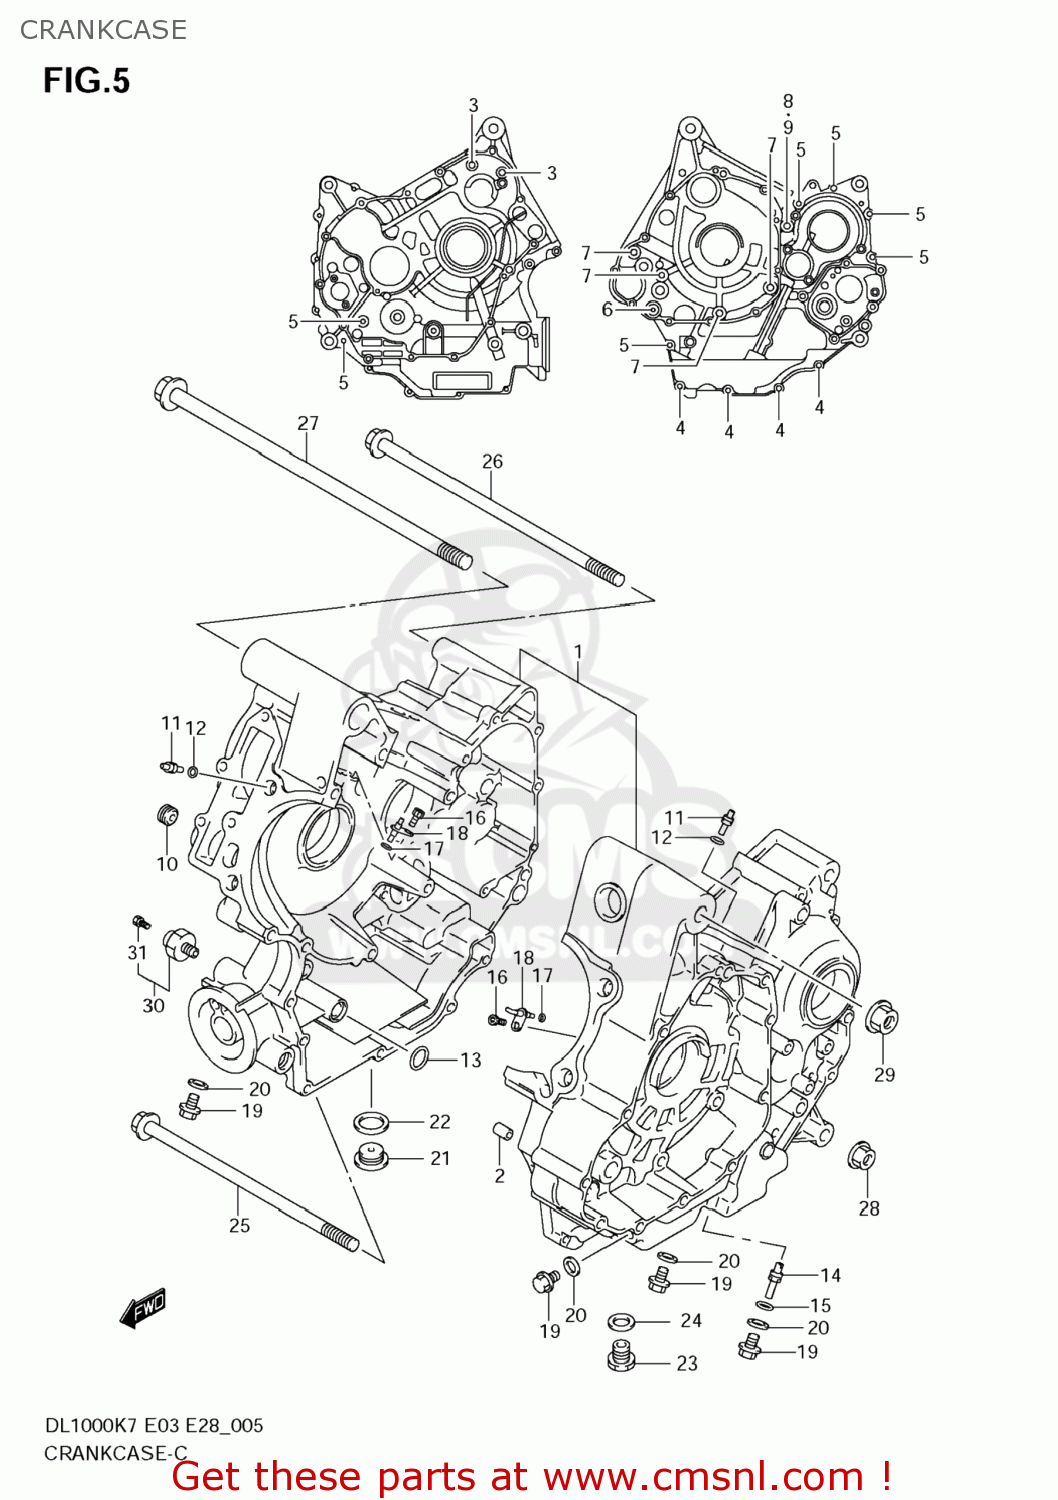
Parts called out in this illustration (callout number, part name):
1	CRANKCASE SET
2	PIN,CRANKCASE
3	BOLT(8X110)
4	BOLT
5	BOLT
6	BOLT
7	BOLT
8	BOLT(8X125)
9	WASHER
10	JET,OIL GALLERY(3.6)
11	JET,AIR(14)
12	O RING(D:1.2,ID:4)
13	O RING(D:1.9,ID:12.6)
14	JET,OIL GALLERY
15	O RING(D:1.2,ID:4)
16	BOLT(6X12)
17	O RING(D:1.2,ID:4.7)
18	JET,PISTON COOLING
19	BOLT
20	GASKET(8.2X14X1) (NAS)
21	PLUG,16X8
22	GASKET(16X22X2) (NAS)
23	PLUG(14X20)
24	GASKET(13.8X18.8X4.8) (NAS)
25	BOLT(10X225)
26	BOLT(10X275)
27	BOLT(12X330)
28	NUT
29	NUT
30	SWITCH ASSY,OIL PRESSURE
31	BOLT,OIL PRESSURE SWITCH
